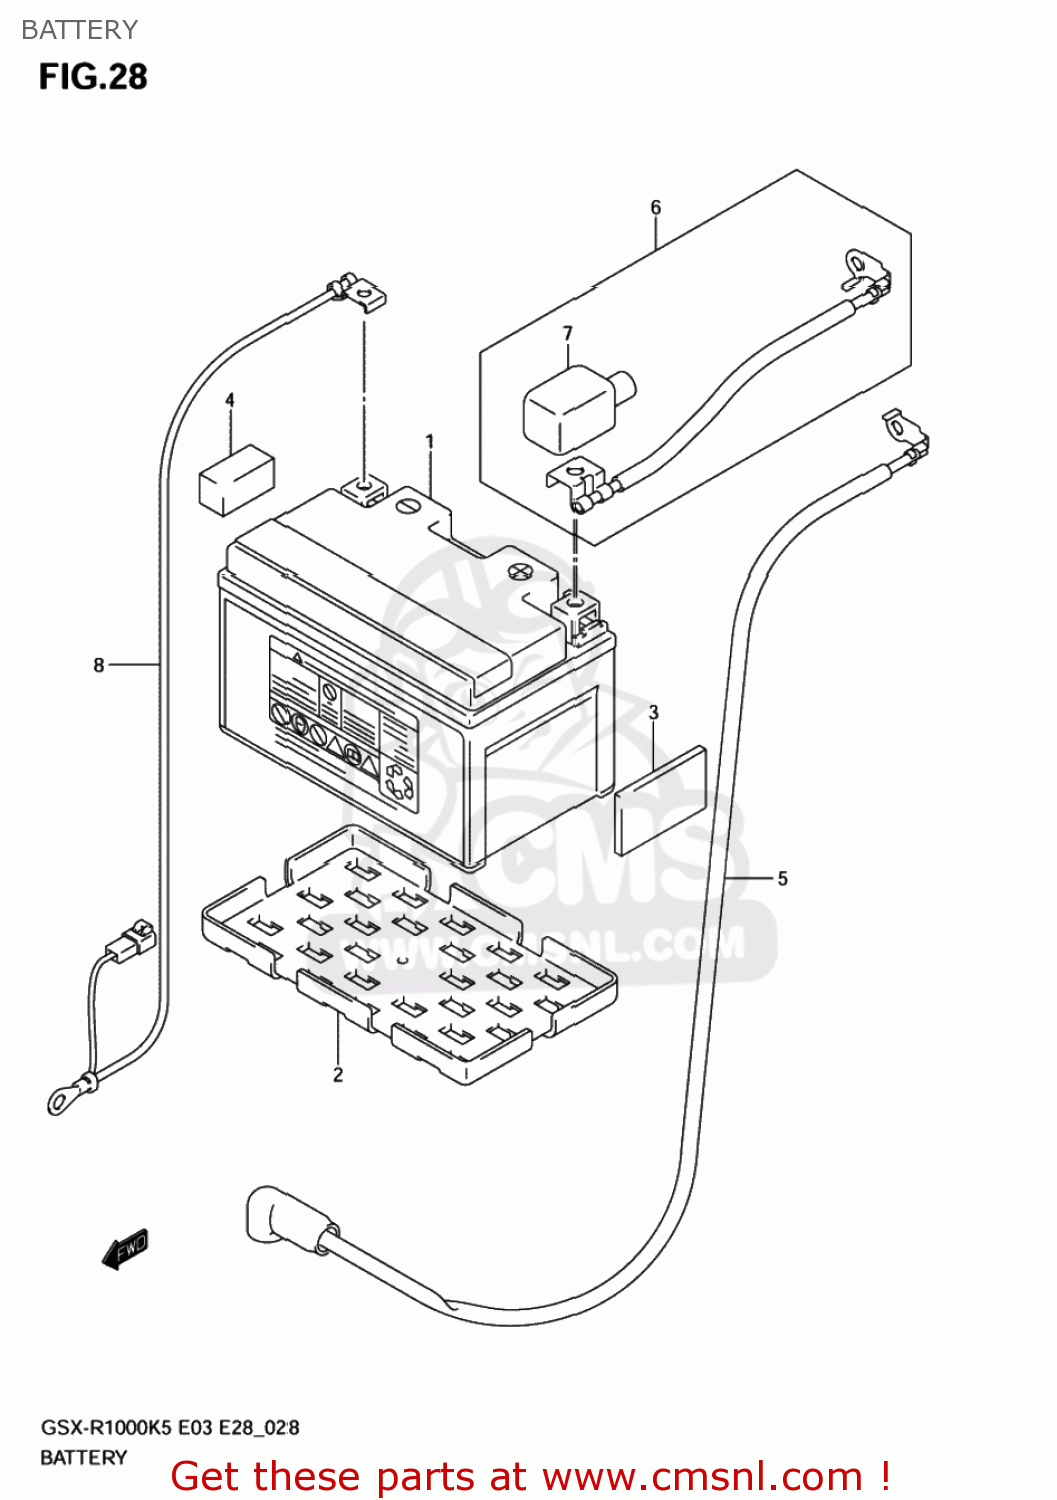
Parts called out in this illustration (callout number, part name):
1	BATTERY ASSY,F
2	PROTECTOR,BATTERY
3	PROTECTOR, BATTERY (50X30X4)
4	PROTECTOR(30X15X14)
5	WIRE,STARTER MOTOR LEAD
6	WIRE,BATTERY PLUS LEAD
7	CAP,BATTERY PLUS
8	WIRE,BATTERY MINUS LEAD
